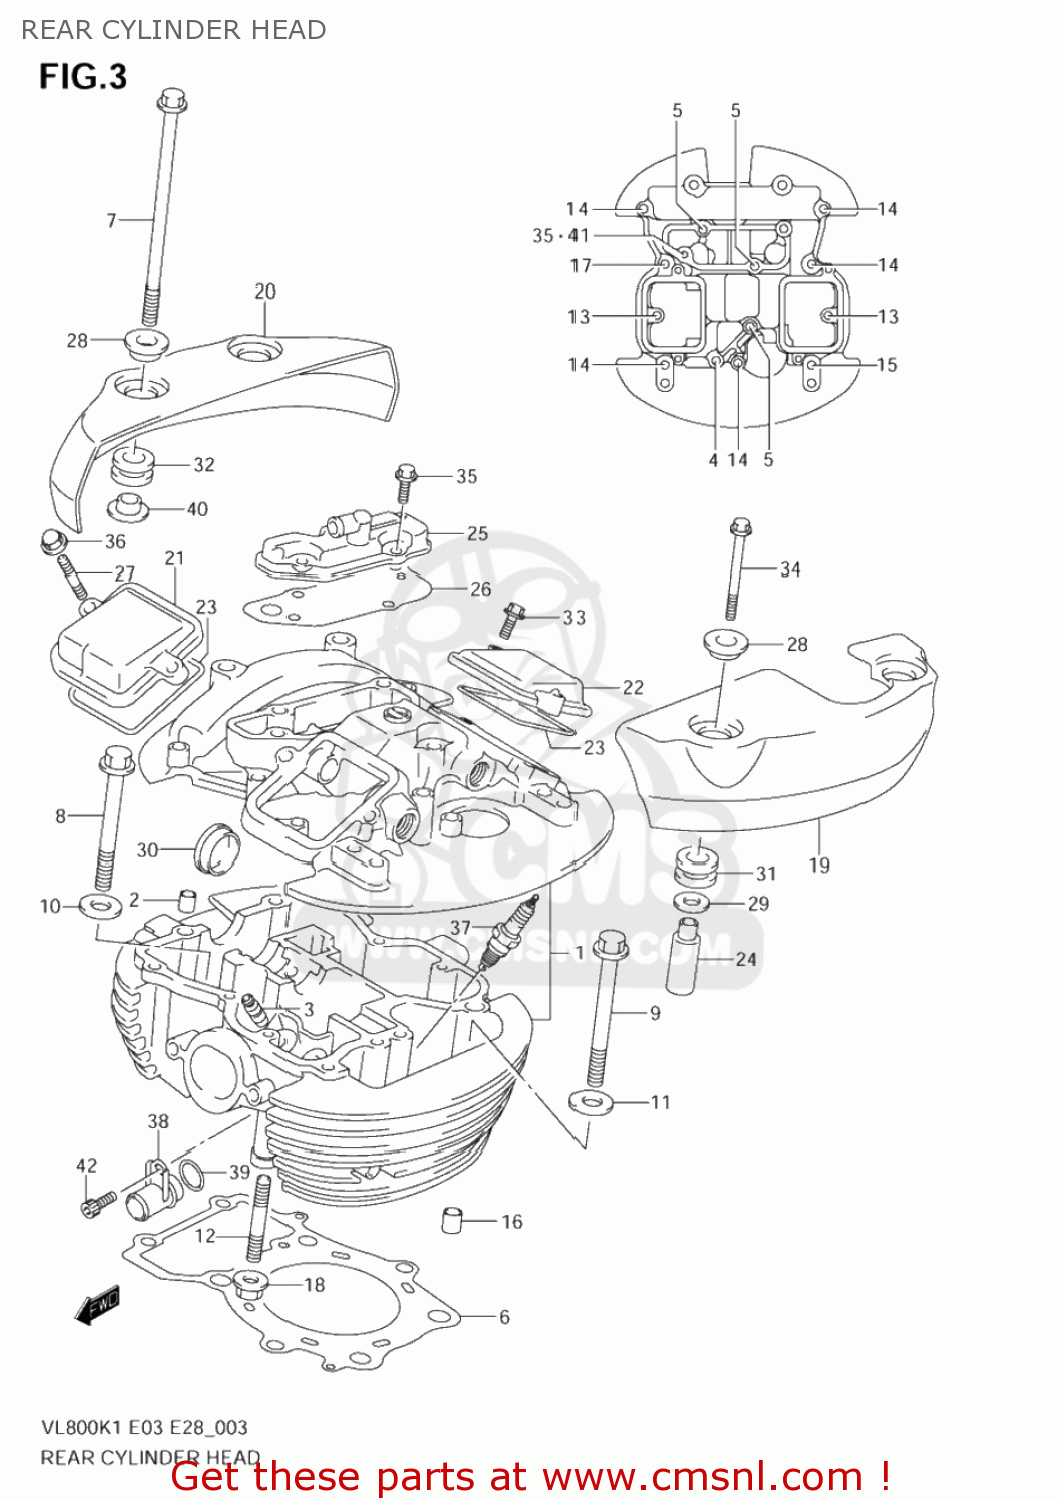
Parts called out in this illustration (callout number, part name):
1	HEAD ASSY,CYLINDER RR
2	PIN(8.4X11X14)
3	GUIDE,VALVE
4	BOLT(6X50)
5	BOLT(6X55)
6	GASKET,CYLINDER HEAD RR (NAS)
7	BOLT(8X250)
8	BOLT(10X155)
9	BOLT(10X165)
10	WASHER(8.5X24X1.6)
11	WASHER(10.5X22X2.3)
12	TAPEIND
13	BOLT
14	BOLT
15	BOLT
16	PIN
17	BOLT
18	NUT
19	CAP,CYLINDER HEAD COVER RL
20	CAP,CYLINDER HEAD COVER RR
21	CAP,INSPECTION INTAKE
22	CAP,INSPECTION EXHAUST
23	GASKET,INSPECTION CAP (NAS)
24	SPACER,CYL HEAD COVER CAP NO.2
25	COVER,BREATHER
26	GASKET,BREATHE (NAS)
27	BOLT,STUD
28	WASHER(6.5X18X1.6)
29	WASHER(9.5X20X1)
30	PLUG(OD:30)
31	CUSHION
32	CUSHION
33	SCREW
34	BOLT
35	BOLT
36	NUT
37	SPARK PLUG X22E
38	UNION,CYL HEAD
39	O RING(D:2.4,ID:15.8)
40	BUSH
41	GASKET(5.8X13X1.2) (NAS)
42	BOLT,STRANGER
